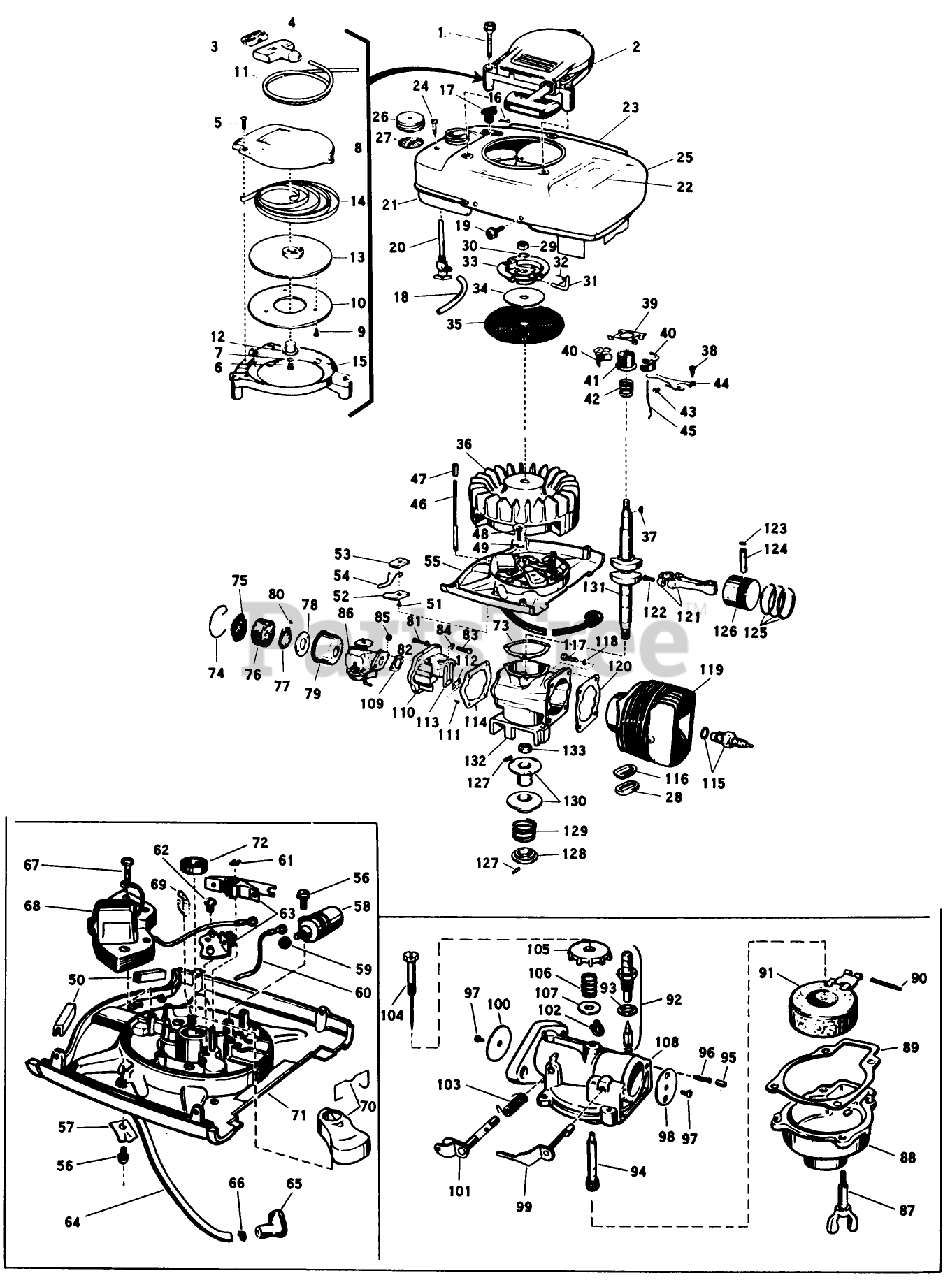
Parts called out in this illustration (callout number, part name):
15	Base-Starter
16	Cotter Pin-Choke Knob
17	KNOB, CHOKE BAR
19	SCREW S
20	VALVE&SCREEN SM
22	Decal-Instruction
23	Decal-"Lawn-Boy"
26	Gas Cap
31	PIN - STARTER
41	COLLAR S
43	WEAR BLOCK S
44	GOVERNER LEVER AY
45	GOVERNOR ROD S
51	Screw Shut-off Switch
61	Spring Clip-Breaker Post
63	BREAKER AY. S
65	Cover-Rubber
69	Oiler Wick
73	GASKET S
76	ELEMENT
78	BACK-UP PLATE
81	SCREW S
85	STOP NUT
97	Screw-Choke Disc
99	CHOKE SHAFT&LVR AY
103	SPRING
104	NEEDLE AY. S
106	Spring-Ndl. Adj.
109	GASKET S
112	PLATE-BACKUP, REED
115	Spark Plug
122	Screw-Connecting Rod
127	Pin-Pulley Drive
128	Retainer-Spring (Drive Pulley)
129	Spring-Comp. (Drive Pulley)
131	Crankshaft
